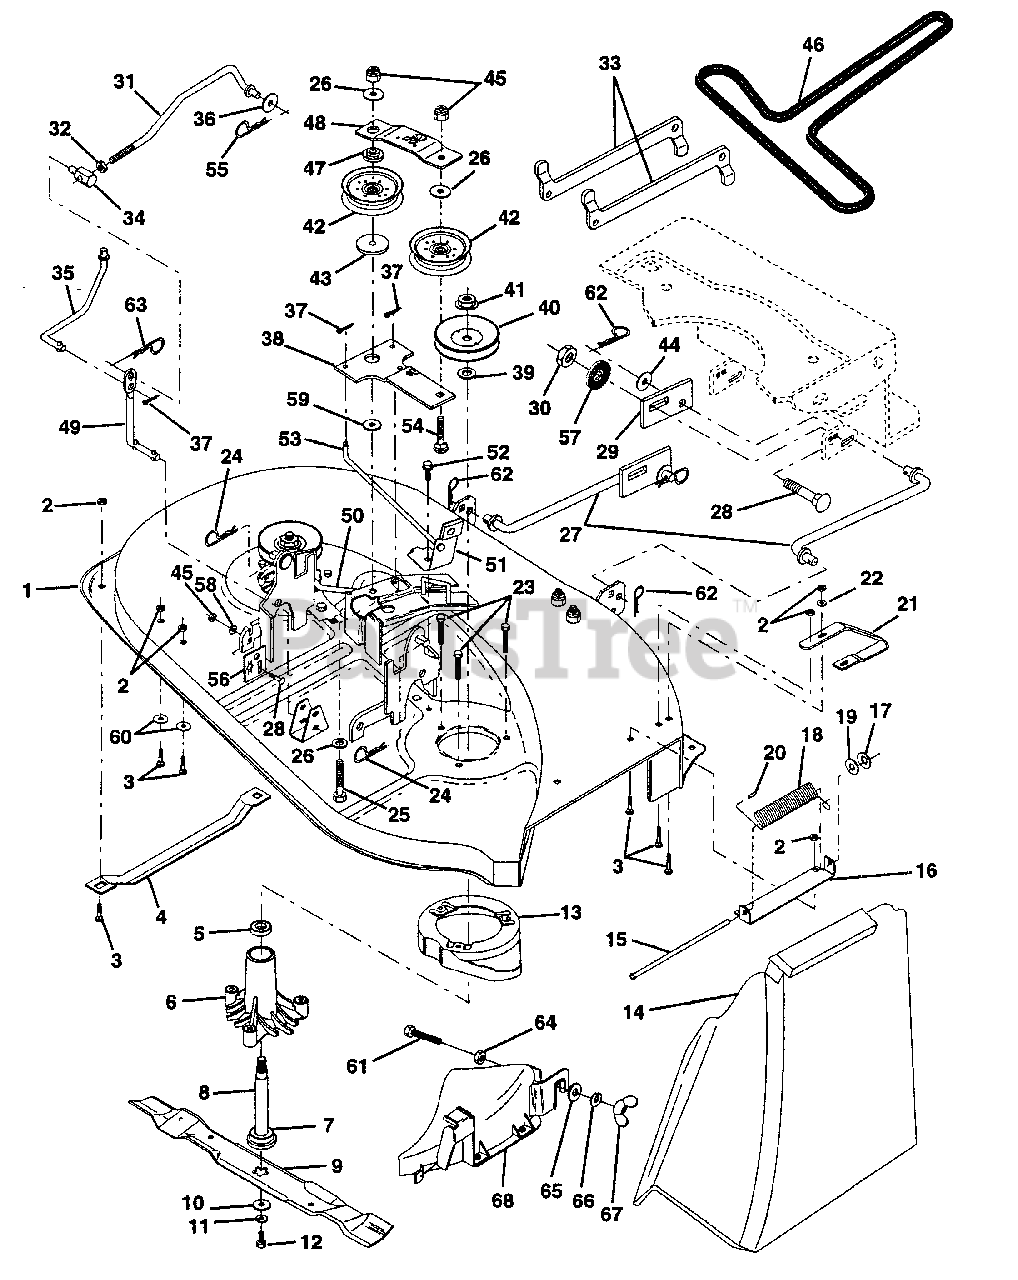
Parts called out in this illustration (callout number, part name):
1	Mower Deck Assembly
2	Nut, Lock Hx w/Ins 5/16-18
3	Bolt, Carriage 5/16-18 x 3/4
4	Runner, L.H.
6	Housing, Mandrel
8	Shaft and Bearing Assembly, Mandrel
10	Washer, Hardened
11	Washer, Lock 3/8
12	Bolt, Hex 3/8-24 x 1-1/4 Grade 8
13	Stripper, Mower, Vented
14	Shield, Deflector
15	Rod, Hinge
16	Bracket Assembly, Deflector
18	Spring, Deflector
19	Washer 11/32 x 5/8 x 16 Gauge
20	Cap, Sleeve
21	Runner, R.H.
22	Washer 11/32 x 3/4 x 16 Gauge
23	Bolt 5/16-18 x 1.25
24	Retainer, Spring
25	Bolt, Hex 3/8-16 x 2-1/4
26	Washer 13/32 x 1 x 12 Gauge
27	Link Assembly, Front
28	Bolt, Carriage 3/8-16 x 1
29	Plate Slide Link
30	Nut, Lock Hex w/washer 3/8-16
31	Clutch Rod, Primary
32	Nut, Hex, Jam 3/8-16
33	Arm, Suspension, Rear
34	Trunnion 3/8-16
35	Clutch Rod, Secondary
36	Washer 13/32 x 13/16 x 16 Gauge
37	Pin, Cotter 3/32 x 3/4
39	Washer .150 Thick
40	Pulley, Mandrel
41	Nut, Flangelock 9/16
42	Pulley, Flat Idler
43	Spacer, Retainer
44	Washer 1/2 x 1-1/4 x 16 Ga.
45	Nut, Crownlock 3/8-16
47	Spacer, Idler Arm
48	Stiffener, Idler Arm
49	Rod, Pivot
50	Rod, Brake, L.H.
51	Brake Assembly
52	Screw, Hex Wsh Hd, Thdrol. 5/16-18 x 3/4
53	Rod, Brake, R.H.
54	Bolt, Carriage 3/8-16 x 1-3/4 Gr. 5
55	Spring, Retainer
56	Adjustment Plate, Rear Link, L.H.
57	Washer 13/32 x 1 Serrated
58	Washer 13/32 x 3/4 x 12 Gauge
59	Washer Hardened
60	Washer 11/32 x 11/16 x 12 Gauge
61	Bolt 3/8-16 x 1-1/4
62	Retainer Spring
63	Retainer Spring
64	Nut, Centerlock 3/8-16
65	Washer 13/32 x 1-1/4 x 16 Ga.
66	Washer Lock 3/8
68	Cover Asm Mulching
